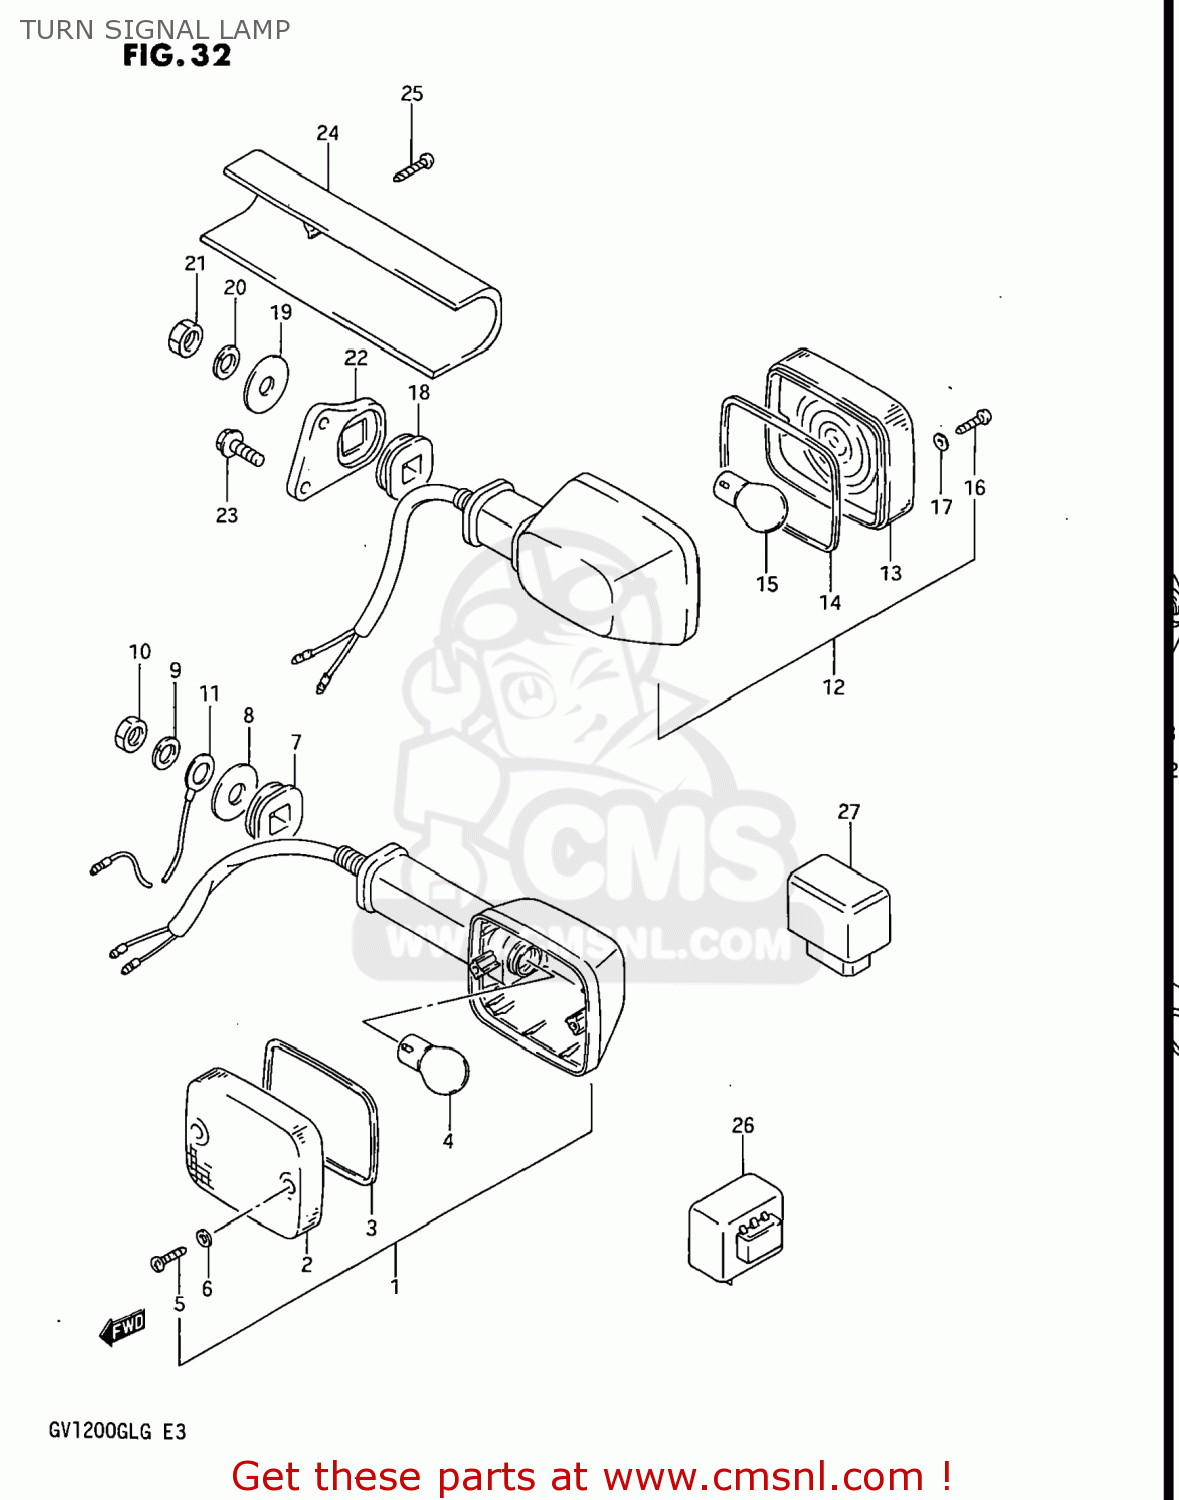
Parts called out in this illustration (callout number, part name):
1	LAMP ASSY,FR TURN SIGNAL
2	LENS
3	GASKET (NAS)
4	BULB(12V23W)
5	SCREW
6	GASKET (NAS)
7	CUSHION
8	WASHER (10.5X30X2.3)
9	LOCK WASHER
10	NUT
11	WIRE
12	LAMP ASSEMBLY,FRONT TURN SIGNAL
13	LENS
14	GASKET (NAS)
15	BULB(12V23W,STANLEY,A4577A)
16	SCREW
17	GASKET (NAS)
18	CUSHION
19	WASHER(10.5X28X2.3)
20	LOCK WASHER
21	NUT
22	BRACKET,RR TURNSIGNAL LAMP
23	BOLT
24	COVER,TURN SIGNAL BRACKET
25	SCREW
26	RELAY ASSY,TURNSIGNAL
27	UNIT,TURN SIGNAL CONTROL
